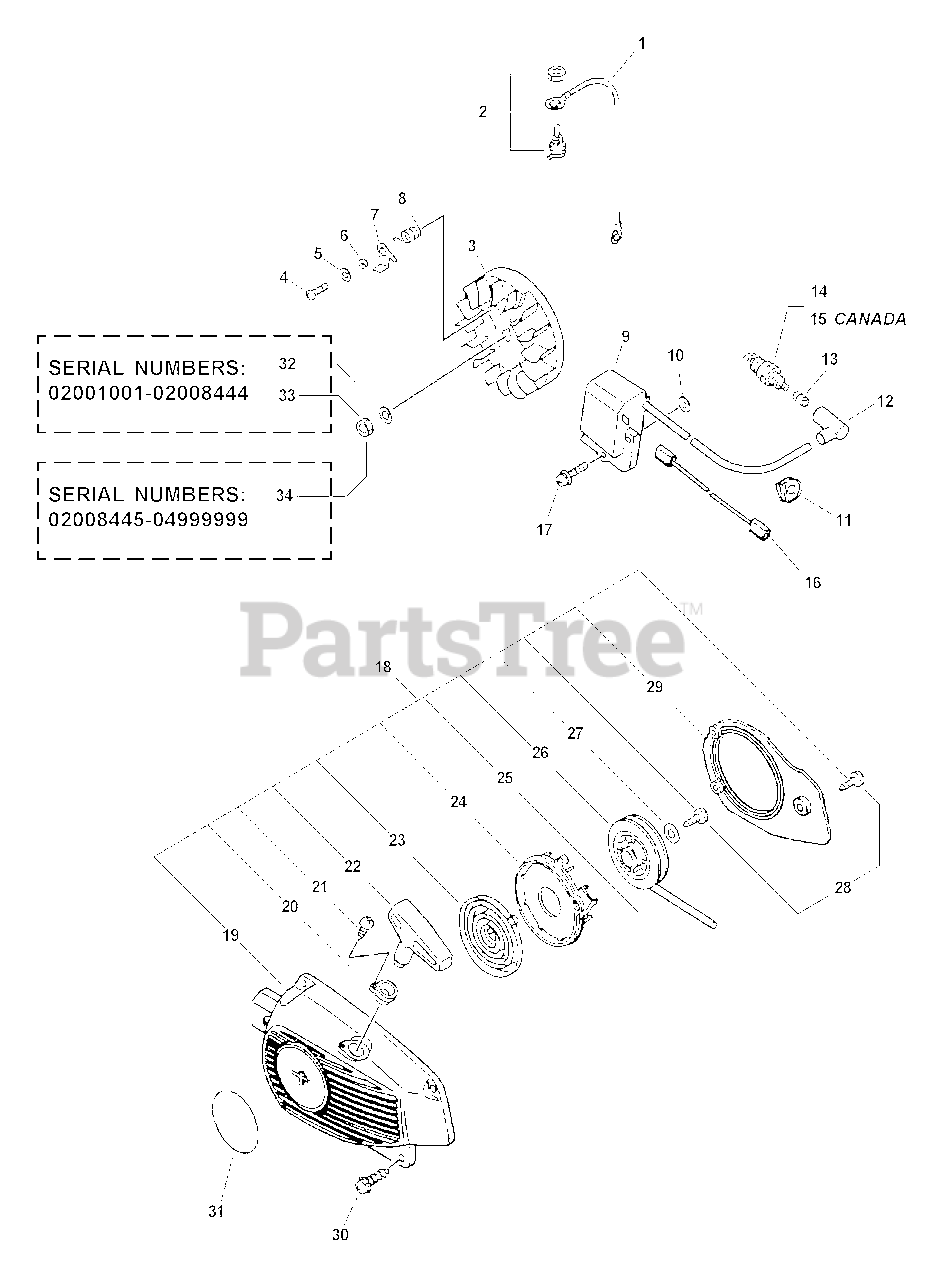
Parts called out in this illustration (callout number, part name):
1	LEAD - GROUND L= 100
2	SWITCH, ON-OFF
3	FLYWHEEL
4	SCREW 5×12
5	WASHER 5.5×12×0.8
6	SPACER 5.2×8×2.1
7	PAWL, STARTER
8	SPRING, TORSION
9	COIL, IGNITION
10	WASHER 5.2×12×3
12	CAP, SPARK PLUG
13	TERMINAL, SPARK PLUG
14	SPARK PLUG - BPM8Y
15	SPARK PLUG - BPMR8Y
16	LEAD - IGNITION L= 95
17	SCREW 5×22
18	STARTER ASSY
19	CASE, STARTER
20	GUIDE, ROPE
21	SCREW 3×14
22	GRIP, STARTER
23	SPRING, RECOIL
24	PLATE, STARTER
25	ROPE, STARTER 3.0×850
26	REEL, ROPE
27	WASHER 4.1×15.5×1T
28	SCREW 4×14
30	SCREW 4×16
31	LABEL, ECHO
32	NUT M8
33	WASHER 8.5×16×1.2
34	NUT, FLANGE M8
